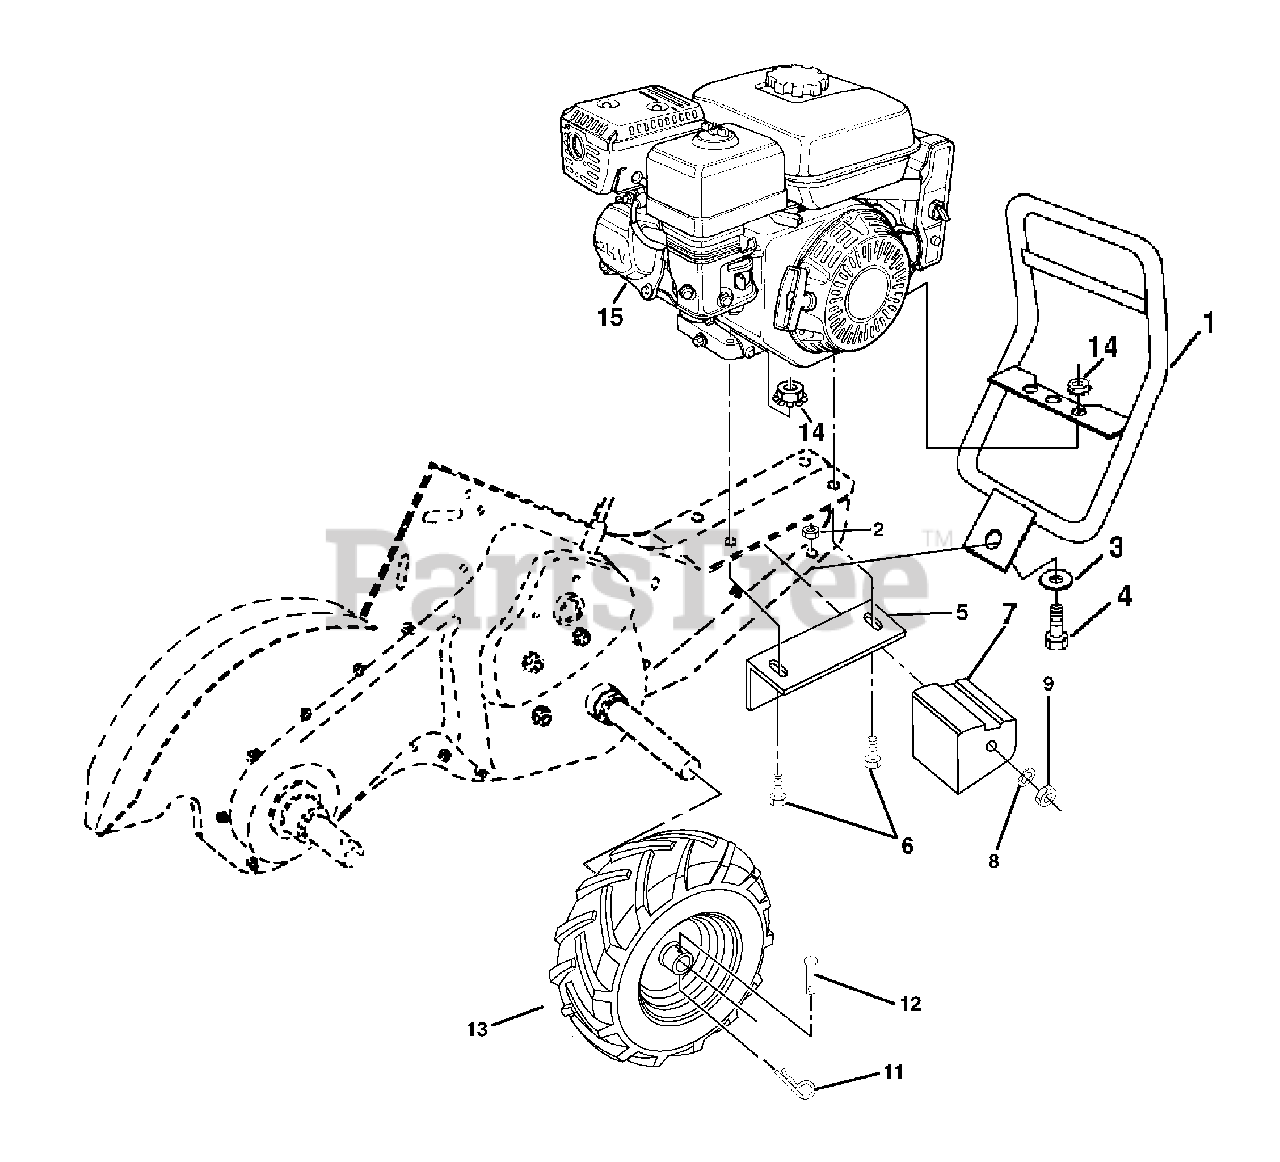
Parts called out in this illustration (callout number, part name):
1	Bumper
2	Nut Lock Hex Flange
3	Washer 11/32 x 11/16 x 16 Ga.
4	Bolt Hex Hd 5/16-18 x 3/4
5	Bracket, Reinforcement
6	Bolt, Hex 5/16-18 x 1-1/2
7	Counter Weight, R.H.
8	Washer, Lock 3/8
9	Nut, Hex 3/8-16
11	Clip, Hairpin
12	Rivet, Drilled
13	Rim
13	Tire Valve
14	Nut, Keps 5/16-18
15	Engine, Honda
